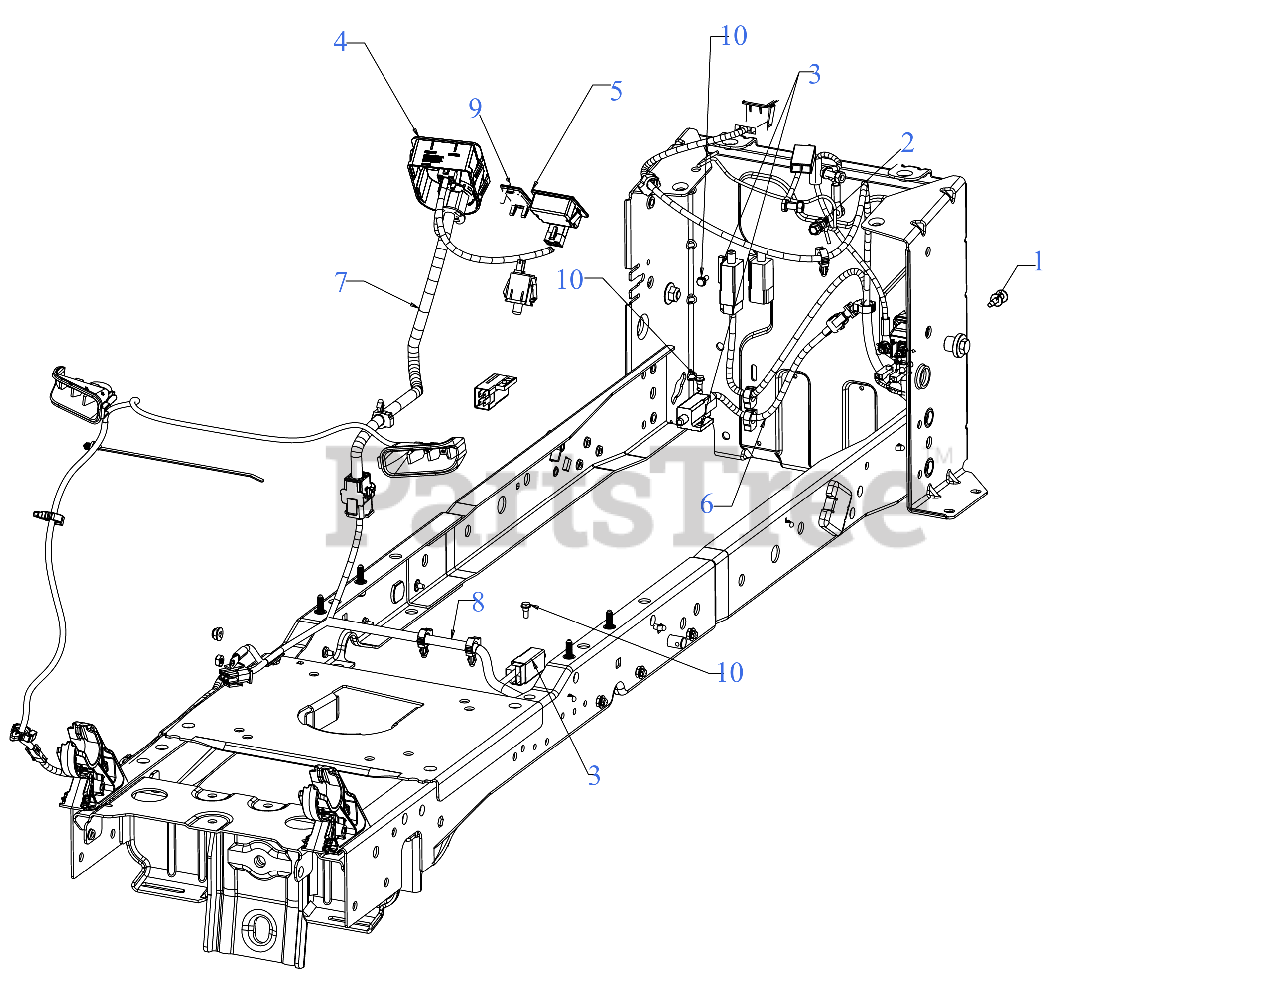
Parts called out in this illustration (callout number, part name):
1	SCREW M6-1 x .625
2	SCREW 1/4-20X.625
3	INTERLOCK SWITCH (NO/NC)
4	IGNITION MODULE SWITCH RMC (MAN PTO BLK)
5	HOUR METER/SERVICE MINDER
5	Cub Cadet HOUR METER KIT
5	Troy-Bilt HOUR METER KIT
6	REVERSE HARNESS
7	DASH HARNESS (M-PTO/RMC/HRMTR)
8	MAIN HARNESS (M-PTO/RMC/HRMTR)
9	DASH PLUG
10	SHOULDER SCREW
